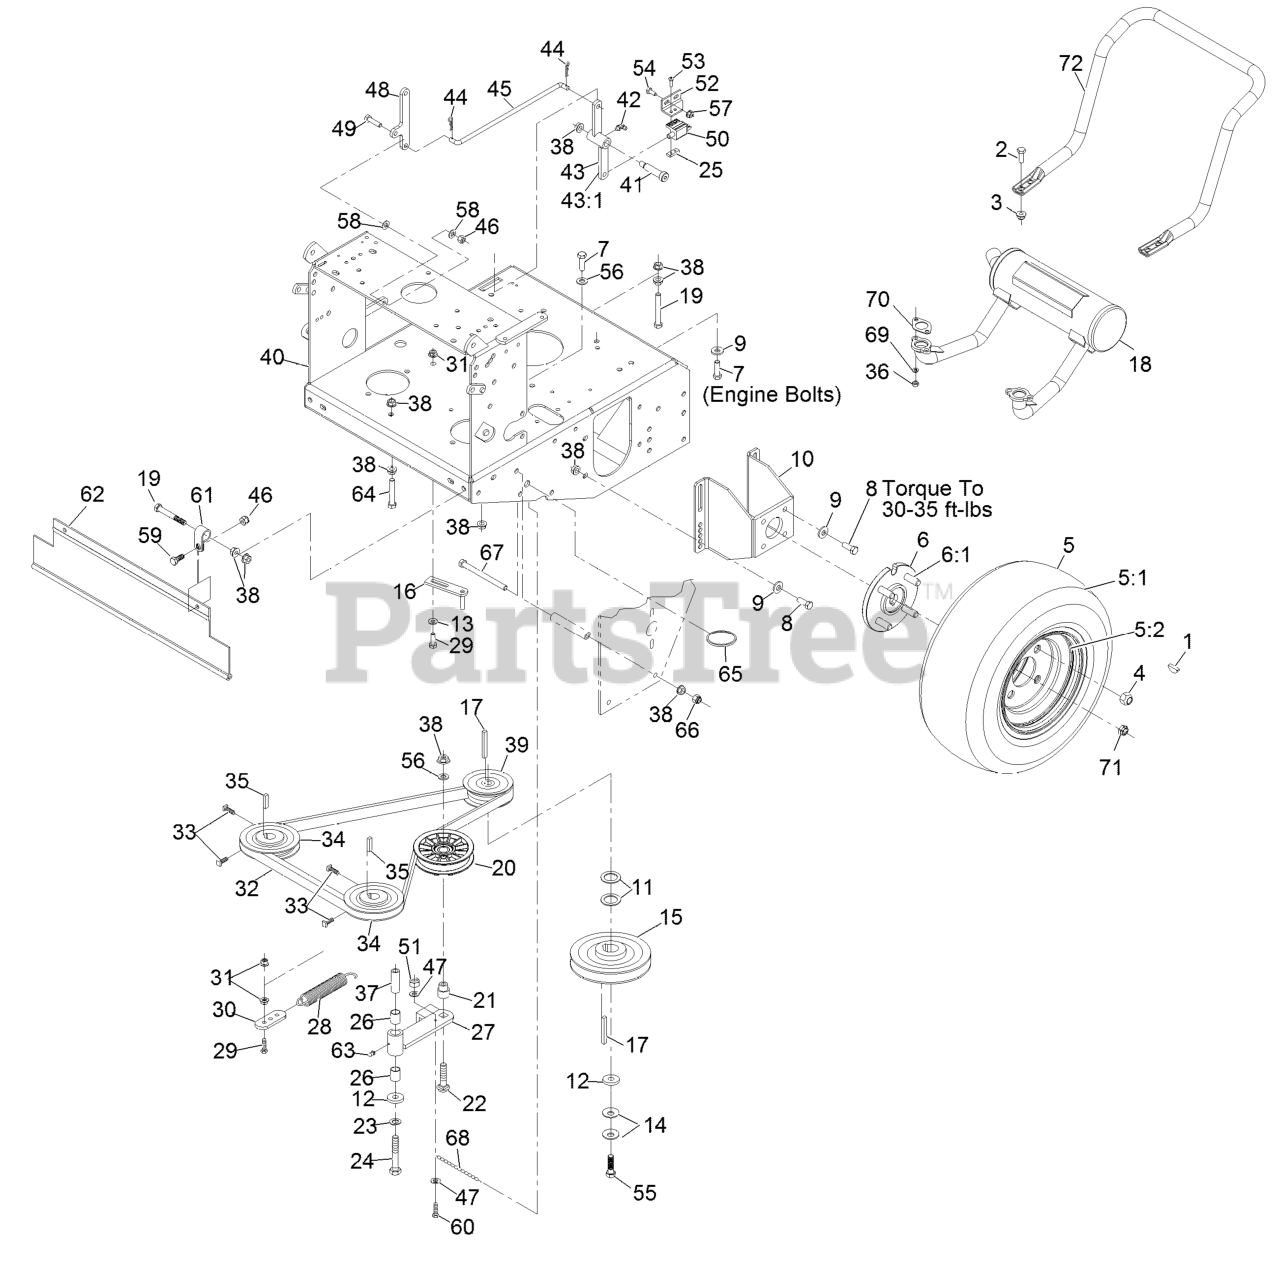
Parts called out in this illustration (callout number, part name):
1	KEY-WOODRUFF
2	SCREW-HH
3	NUT-HF, NI
4	NUT-LUG
5	WHEEL AND TIRE ASM
5:1	TIRE-TURFMASTER
5:2	RIM-WHEEL
6	WHEEL HUB ASM
6:1	STUD-WHEEL
7	SCREW-HH
8	SCREW-HH
9	WASHER-BELLEVILLE
10	MOUNT-MOTOR
11	WASHER-SPACER
13	WASHER-SPRING
14	WASHER-SPRING
16	GUIDE-BELT
18	MUFFLER-HORIZONTAL, OFFSE
19	SCREW-HH
20	PULLEY-IDLER, FLAT
21	BUSHING-IDLER
22	SCREW-CARR
23	WASHER-LOCK
24	BOLT-CARR
25	PLATE-TAPPED
26	SLEEVE-BEARING
27	IDLER ARM ASM
28	SPRING-EXTENSION
29	SCREW-HH
30	ANCHOR-SPRING
32	BELT-COG
33	SCREW-SET
34	SHEAVE ASM
37	BUSHING
38	NUT-HHF, WHIZ
39	PULLEY
40	ASM, VH ENGINE DECK W/DEC
42	FITTING-GREASE, 90 DEG
43	BELLCRANK ASM
44	PIN-COTTER
45	LINKAGE-ENGAGE, BLADE
46	NUT-LOCK, NI
47	WASHER-FLAT
48	BELLCRANK
49	SCREW-HH
50	SWITCH-OPEN, NORMALLY
51	NUT-LOCK, NI
52	BRACKET-SWITCH, BLADE
53	SCREW-PPH
54	SCREW-HH
55	SCREW-HH
56	WASHER-FLAT
58	WASHER-PLAIN
59	SCREW-HH
60	SCREW-HSH
61	CLIP-LOOM
62	SHIELD-DRAG
63	FITTING-GREASE
64	SCREW-HH
65	RING-SPLIT
66	NUT-LOCK, NI
67	SCREW-HH
68	CHAIN-LINK, TWIST
69	WASHER-LOCK
70	GASKET-EXHAUST
71	NUT-LOCK
72	GUARD-MUFFLER
